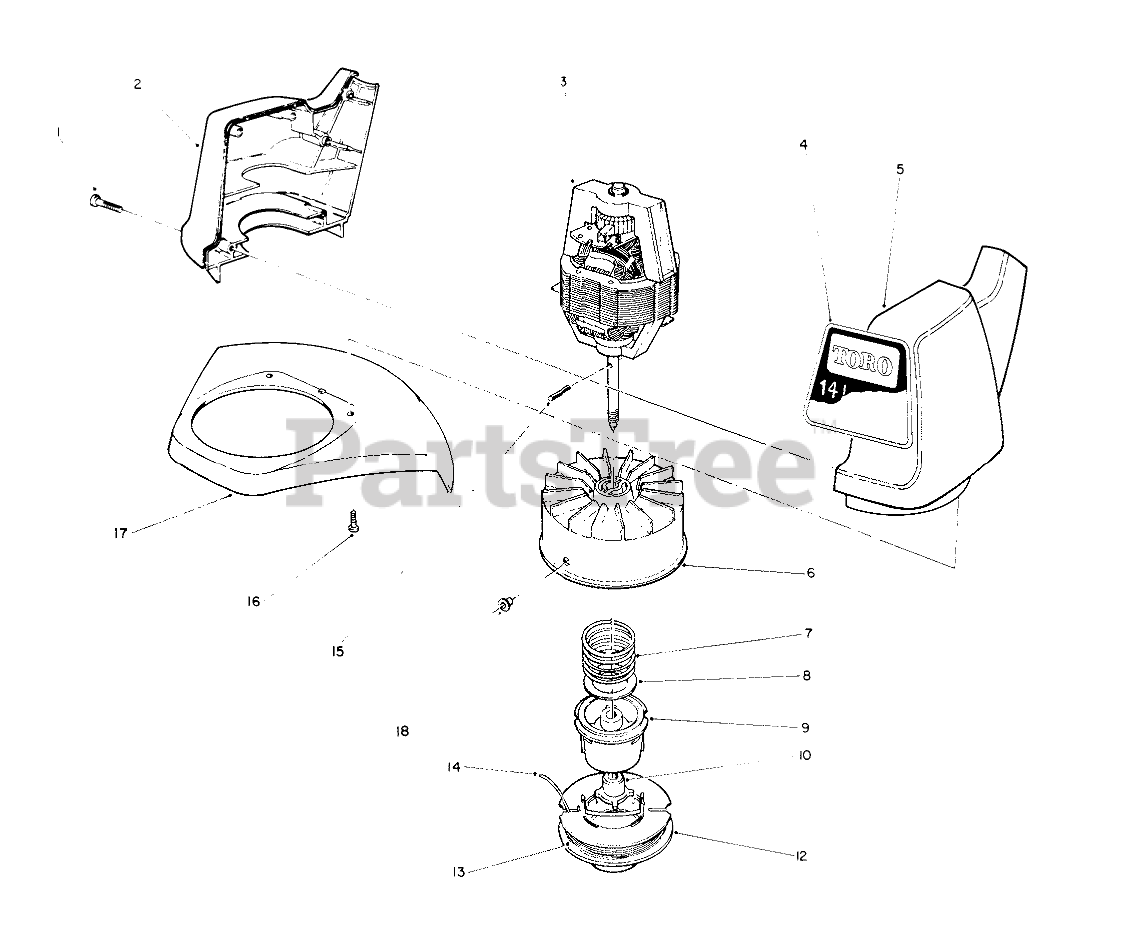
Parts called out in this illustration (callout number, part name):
1	SCREW-PPH
2	RH HOUSING, 14" TRIMMER
3	MOTOR, 1410 TRIMMER
4	1410 DECAL
5	LH HOUSING, 14" TRIMMER
6	Drum & Eyelet Assembly
7	SPRING COMPRESSION
8	WASHER-FLAT
9	SPOOL CORE
10	DRIVER
12	SPOOL CAP
13	Cutting Line (50 .065" Dia.)
14	50-, .065" Dia. Cutting Line In Coil
15	COIL PIN
16	SCREW-PPH
17	Shield Assembly
18	Eyelet
